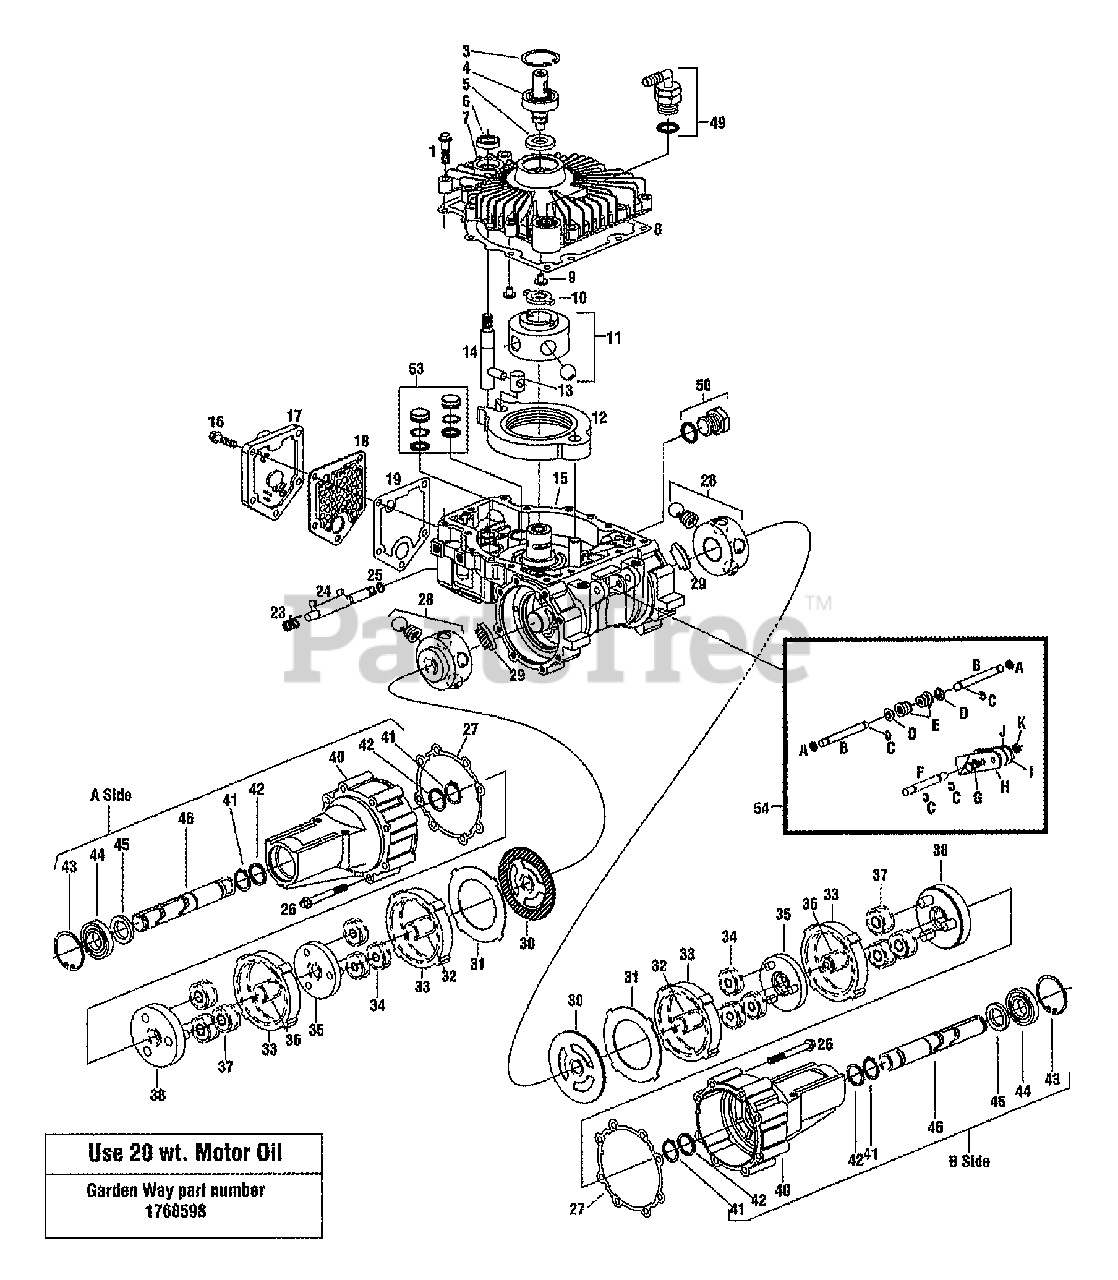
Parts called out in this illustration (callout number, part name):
3	RING-RETAINING
4	SHAFT-INPUT
5	SEAL-OIL
6	SEAL-CONTROL SHAFT
7	COVER
8	COVER-GASKET
9	BUTTON
10	DRIVE
11	PUMP ROTOR/BALL/PIN (S/A)
12	CAM RING
13	INSERT
14	SHAFT-CONTROL EXT THREAD
15	HOUSING
17	FILTER BASE "L"
18	FILTER
19	GASKET
23	VALVE-SPRING DUMP
24	BRACKET
25	RING-O
27	GASKET-AXLE HSG
28	15T MOTOR ROTOR/BALL
29	PAD-FRICTION
30	PLATE-REACTION
31	PLATE-BACKUP
32	15T SUN GEAR, FIRST
33	GEAR-RING 57T
34	GEAR-PLANET
35	PRIMARY CARRIER
36	15T SUN GEAR, SECOND (STEEL)
37	21T PINT. GEAR (S/A) SECOND STEEL
38	SECOND CARRIER
40	AXLE-HOUSING
41	RING-RETAIN EXT
42	WASHER-THRUST
43	RING-RETAIN INT
44	BEARING
45	SEAL-RADIAL LIP
46	AXLE-SHAFT
49	90 DEGREE FITTING/O-RING (S/A)
50	PLUG O-RING (S/A)
53	PISTON
54	BRAKE LEVER PARTS
54A	SEAL-QUAD
54B	ROD-PUSH
54C	RING-RETAIN "E"
54D	BASE-SPRING
54E	SPRING-CONICAL
54F	BRAKE-SHAFT
54G	SCR-HH
54H	LEVER-BRAKE RH
54I	LEVER-BRAKE LH
54K	NUT-HEX LOCK
